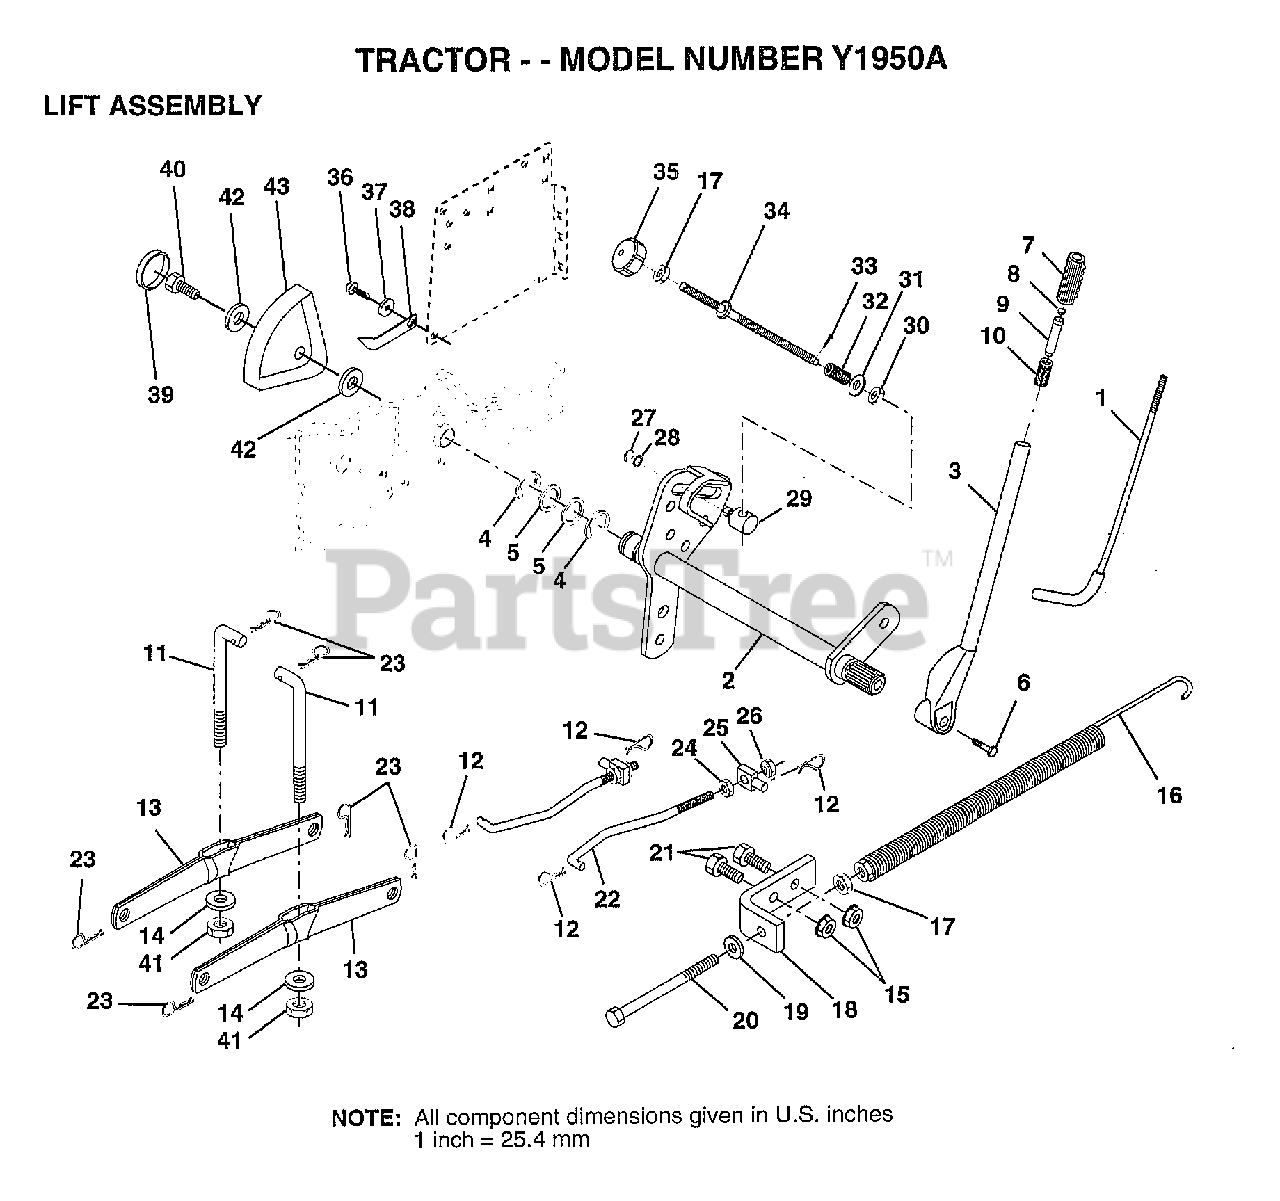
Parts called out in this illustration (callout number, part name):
1	LEVER ROD LT
2	"SHAFT,LIFT"
4	E-RING
5	WASHER
6	"BOLT,HEX"
7	GRIP
10	SPRING T
11	LINK.LIFT.MWR.VGT
12	RETAINER.SPRING
13	ARM SUSP REAR
14	BEARING PVT LH
17	NUT
18	BRACKET SPRING AS
19	WASHER
20	BOLT-ADJ SPRING T
21	BOLT
22	LINK.FRONT
24	NUT
25	TRUNION
26	NUT.LK.W/WSH.1/2.
27	KLIP RING
28	WASHER
29	TRUNION LT
30	NUT T
31	WASHER
32	SPRING.COMP.INF.H
34	ROD.ADJ.LIFT
35	KNOB INF 3/8-16
36	SCREW
37	WASHER T
38	POINTER HGT IND
39	"PLUG,HOLE"
40	SCREW
41	NUT.CROWNLOCK.3/8
42	WASHER
43	HEIGHT INDICATOR
